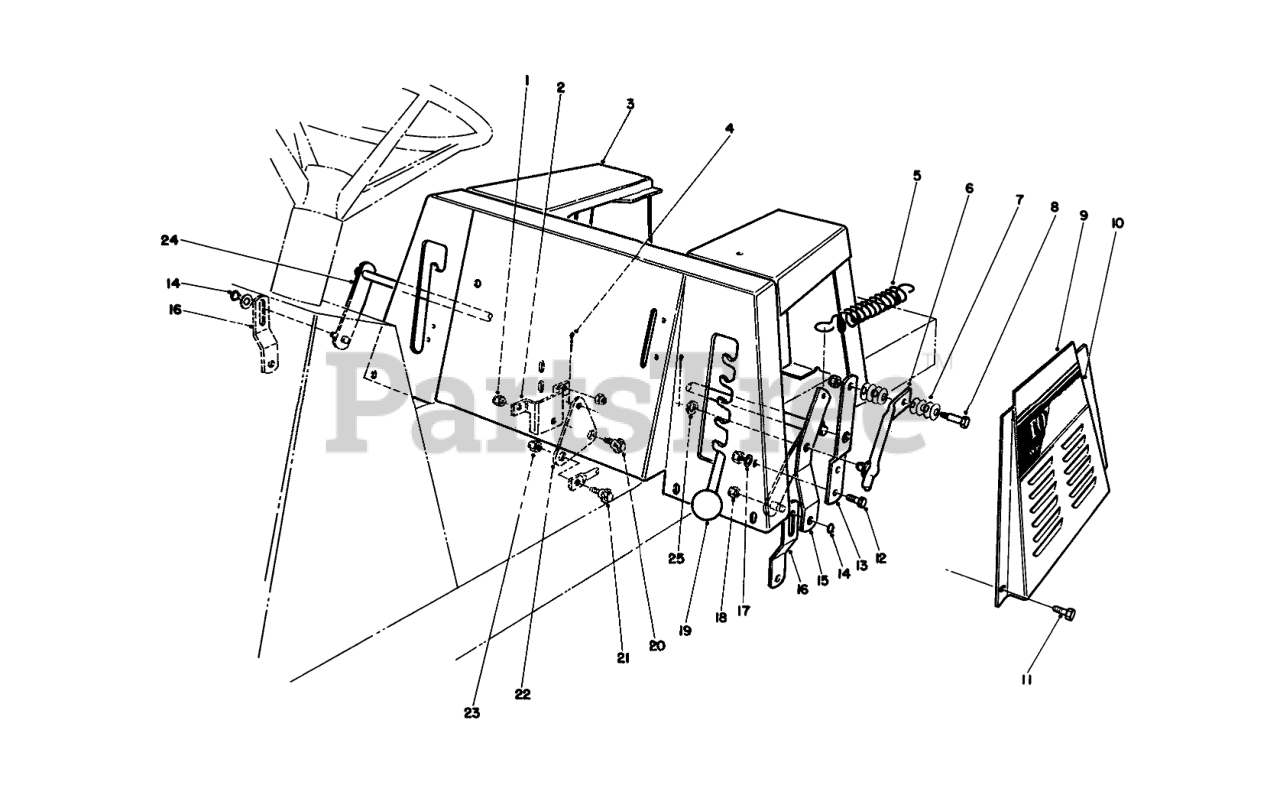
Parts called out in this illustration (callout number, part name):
1	NUT-LOCK, NI
2	BRKT-B.CRANK MTG
3	SEAT BODY WA R
4	PIN-COTTER
5	SPRING-EXTENSION
6	HOC LEVER WA B
7	WASHER-BELLEVILLE
8	BOLT-SHOULDER
9	L/H SEAT BASE PANELR
10	DECAL - LH TORO 8-32
11	SCREW-HH
12	SCREW-HH
13	Bracket
14	RING-RETAINING
15	Bracket-H.O.C., Engage
16	Link-Deck Suspension
17	WASHER-PLAIN
18	NUT-LOCK, NI
20	SCREW-SHOULDER
21	SCREW-SHOULDER
22	BELLCRANK
23	NUT-HEX
24	Arm
25	WASHER-FLAT
